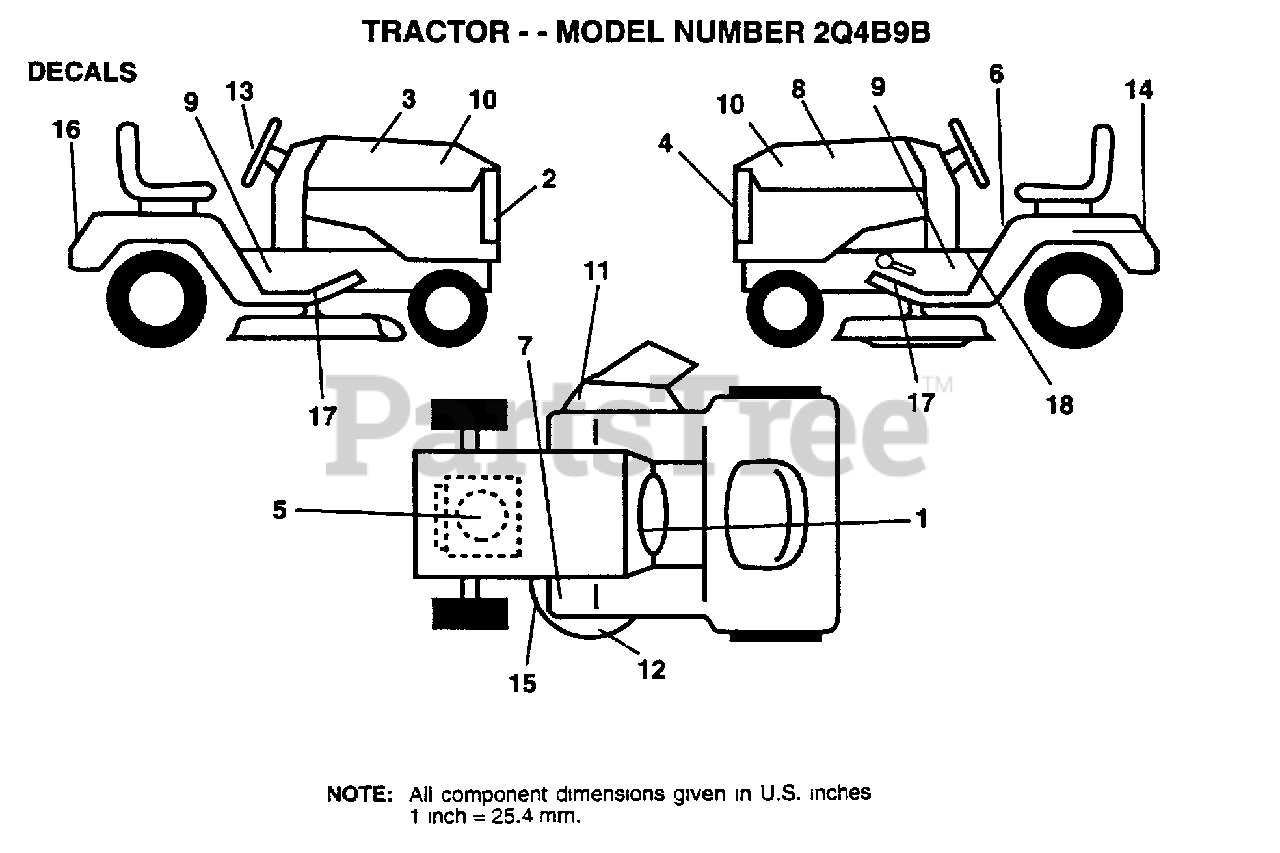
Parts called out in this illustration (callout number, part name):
1	DECAL.DASH.INSTR.
2	GRILL DECAL
3	DECAL HOOD RH RLY
5	DECAL, ENGINE
6	DECAL CAUTION
7	DECAL T
8	DECAL HOOD LH RLY
9	CHASSIS DECAL
10	DECAL.INS.HD.RALL
11	"DECAL, WARNING"
13	"DECAL,STR WHL"
14	DECAL
15	DECAL
16	FENDER DECAL
17	"PAD,FOOTREST"
18	DECAL BRAK PARK
